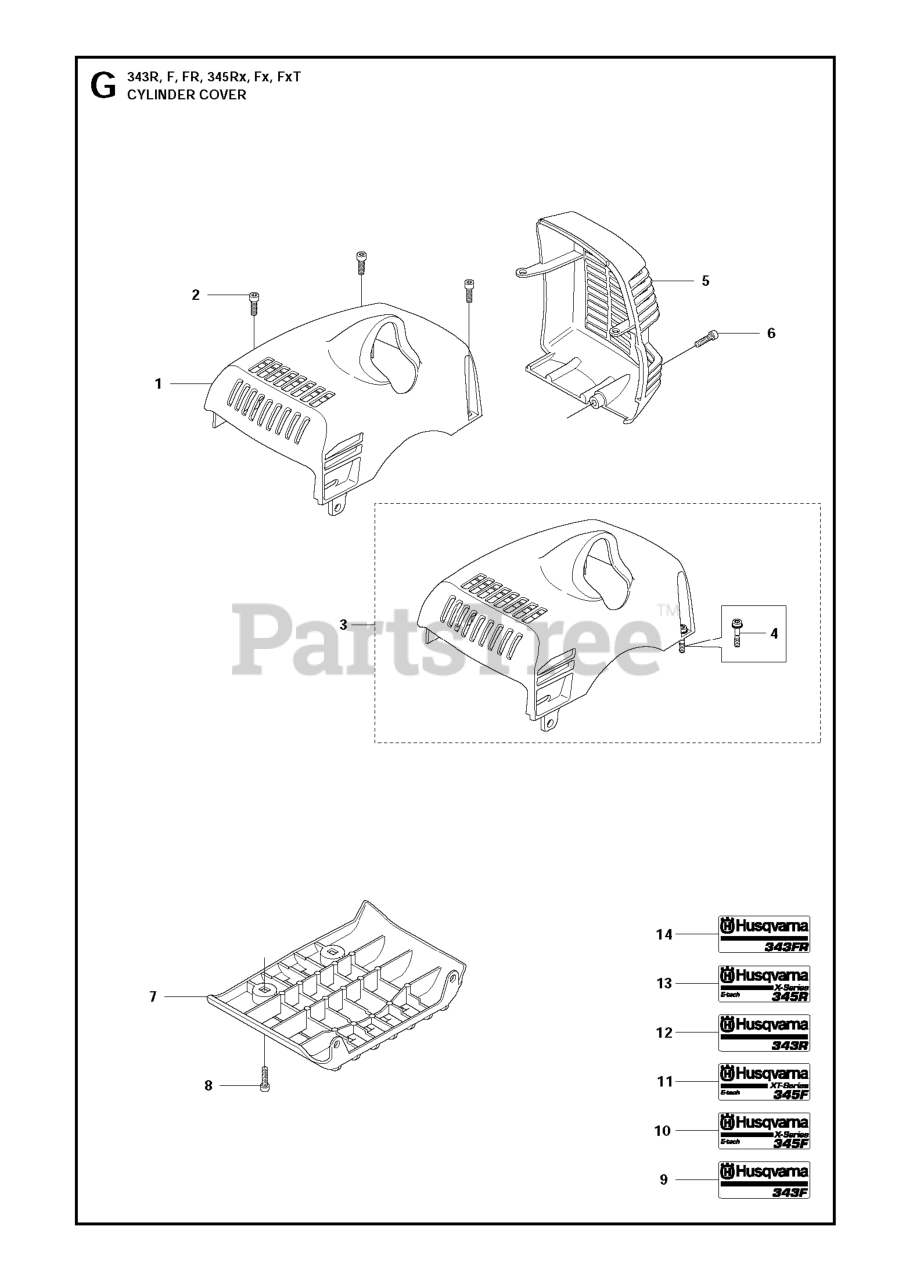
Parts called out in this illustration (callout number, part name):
1	CYLINDER COVER
2	SCREW IHSCFM
3	CYLINDER COVER ASSY
4	SCREW IHSCFMO
5	MUFFLER COVER
6	SCREW IHSCFM
8	SCREW IHSCFM
9	LABEL
10	DECAL
11	DECAL
12	DECAL
13	DECAL
14	LABEL
